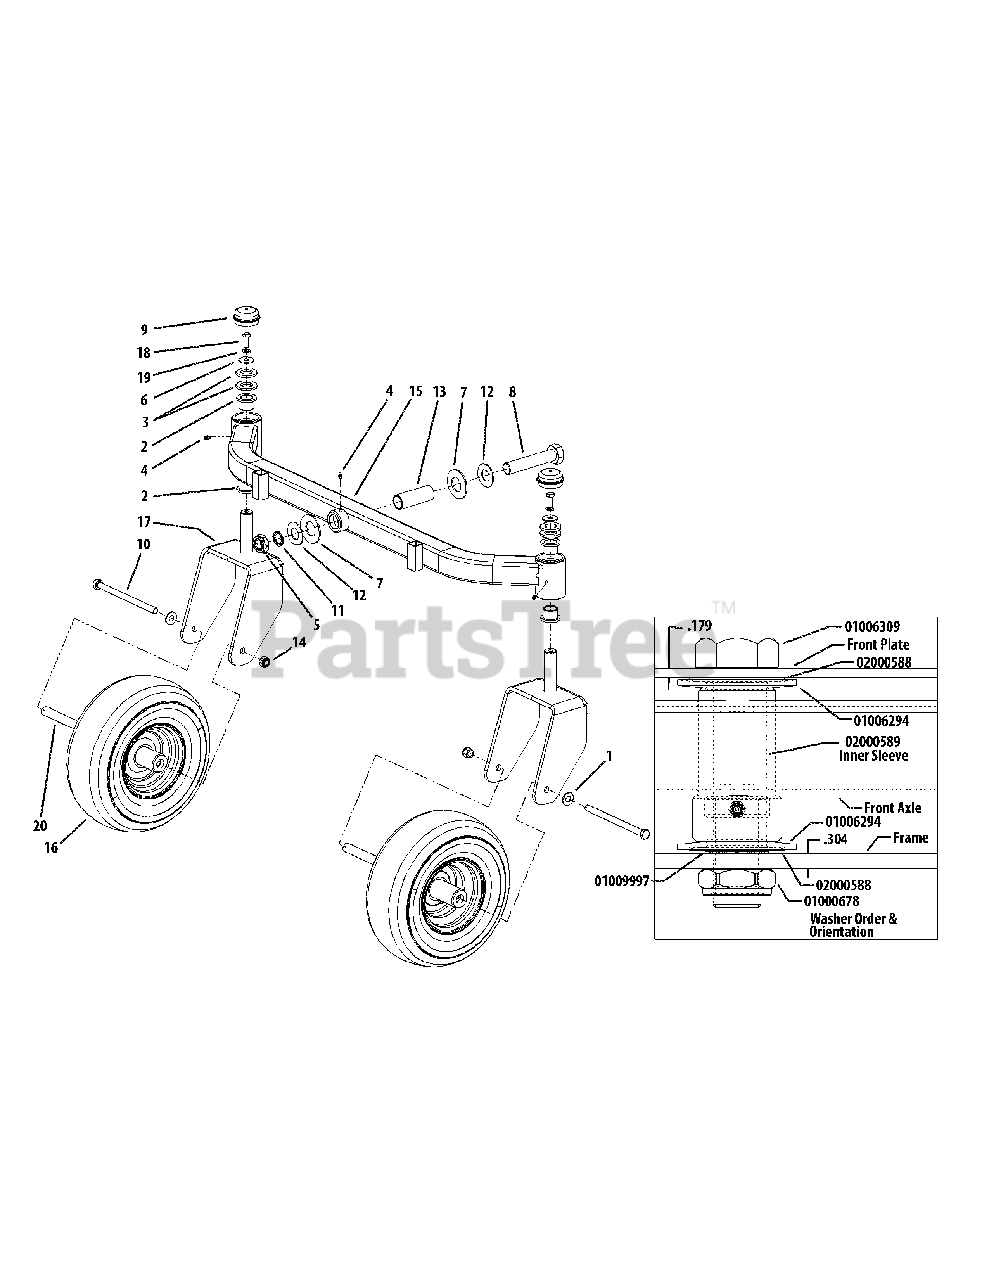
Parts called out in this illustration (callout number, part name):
1	Washer, 1/2 x 1 Shim
2	Flange Bearing, 1.013 ID
3	Washer Special
4	Grease Fitting, 1/4-28 x 3/16
5	Nut, Jam, 1.0-14, Insert Lock
6	Flat Washer, 1.25 x .411 x .100
7	Bell Washer, 1.25 ID x 2.5 x .157
8	Hex Cap Screw, 1-14 x 5.0
9	Grease Cap, 1.986 OD
10	HHCS, 1/2-20, 7.50
11	Retainer Extension, Self Locking
12	Flat Washer, 1.00 ID
13	Spacer, 1.005 ID x 1.25 OD x 3.6
14	Lock Nut, Nylon Insert, 1/2-20
15	Front Axle Assembly (60")
15	Front Axle Assembly, Straight (48")
16	Wheel, 13 x 5.00 x 6.0, includes:
16	Roller Bearings (per tire)
16	Retainer Bushings (per tire)
17	Castor Wheel Mounting Bracket
18	Hex Cap Screw, 3/8-16 x 1.00
19	Lock Washer, 3/8
20	Spacer, .51 ID x .75 OD x 5.825
